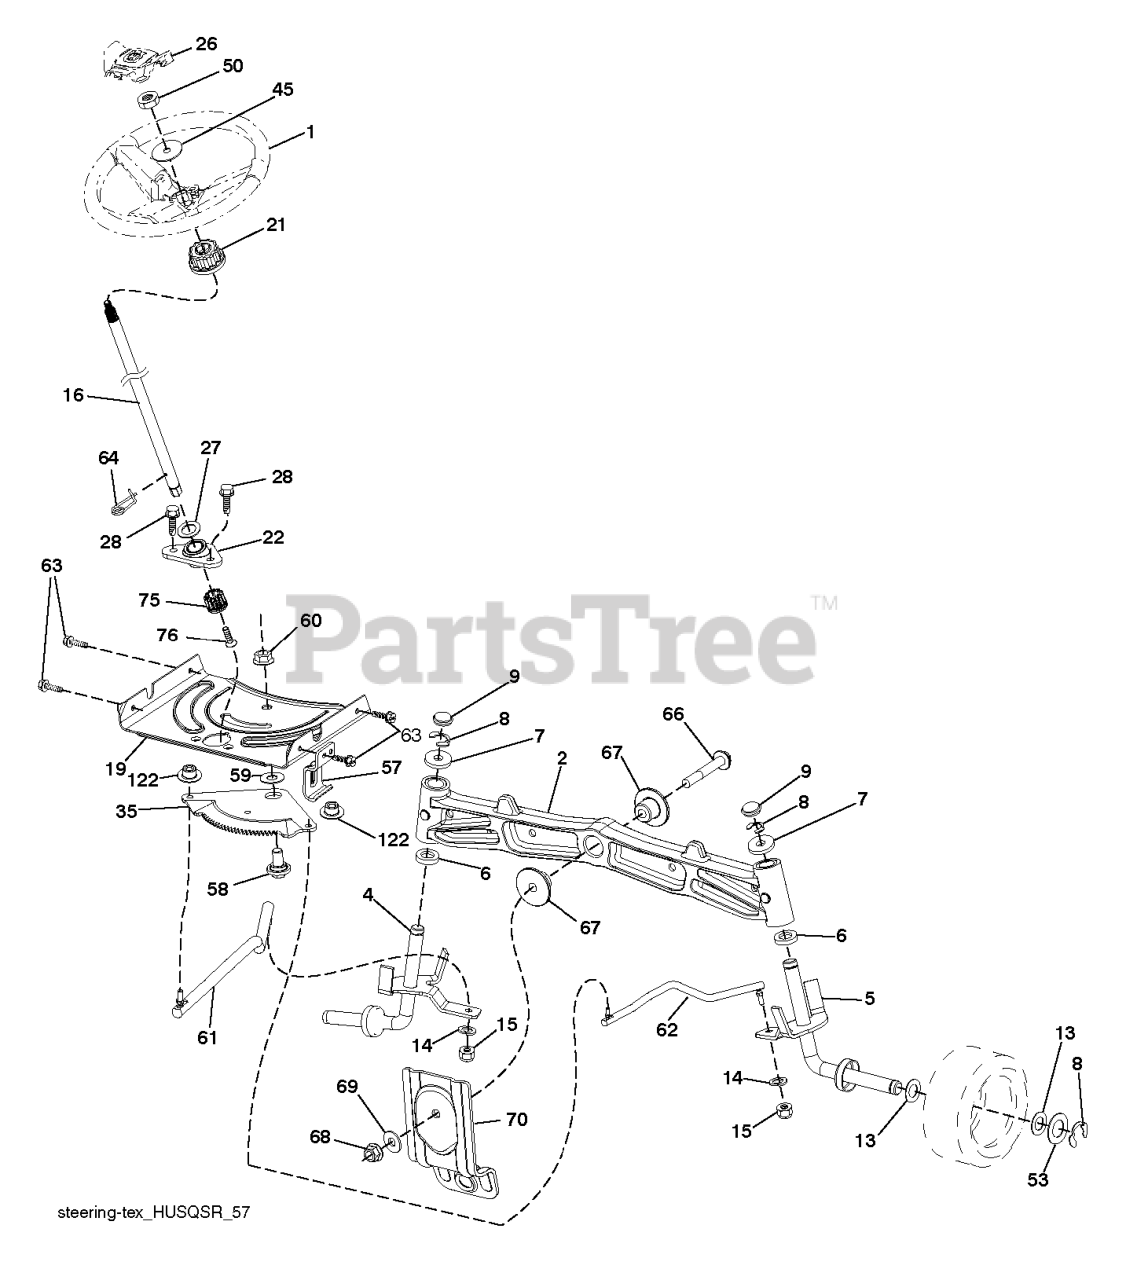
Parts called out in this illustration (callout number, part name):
1	WHEEL.STEER.HUSQ.SR.498.OVMLD
2	AXLE.CAST.IRON
4	SPINDLE.WELDED.LH.16"TEX
5	SPINDLE.WELDED.RH.16"TEX
6	THRUST WASHER
9	CAP.SPINDLE.BLACK
14	WASHER, LOCK 3/8
15	NUT CROWNLOCK 3/8-24
16	SHAFT, STEERING
19	PLATE.STEER.DDL.NLT/NG
21	ADAPTER, WHEEL STNG..
22	STEERING.SUPT.LOWER.
26	INSERT.CAP.WHL.STRG.HUSQ.PREM
28	SCREW, 3/8-16X3/4
35	GEAR.SECTOR.PLATE.DDL.
45	WASHER 9/16"ID, 2 3/8"OD
51	NUT.HEX.1/2-20
53	WASHER.HARDENED
57	BRKT.UPSTOP.GT/LT.TEX
58	BOLT.SHOULDER.SECTOR.P
59	WASHER.THURST.SECTOR.S
60	NUT FLANGE LOCK 5/8-11
61	DRAGLINK.LH.BALLSTUD.D
62	DRAGLINK.RH.BALLSTUD.D
63	SCREW
64	RETAINER.CLIP.SPRING.S
66	BOLT HEX FGHD 7/16-14 X 3 SERR
67	BUSHING.PM.FRONT AXLE
68	NUT.LOCK.FLANGE.7/16
69	WASHER.1.5X.505X.118
70	BRKT.DECK.SUSPENSION.F
122	CAP.GEAR.SECTOR.TEX
